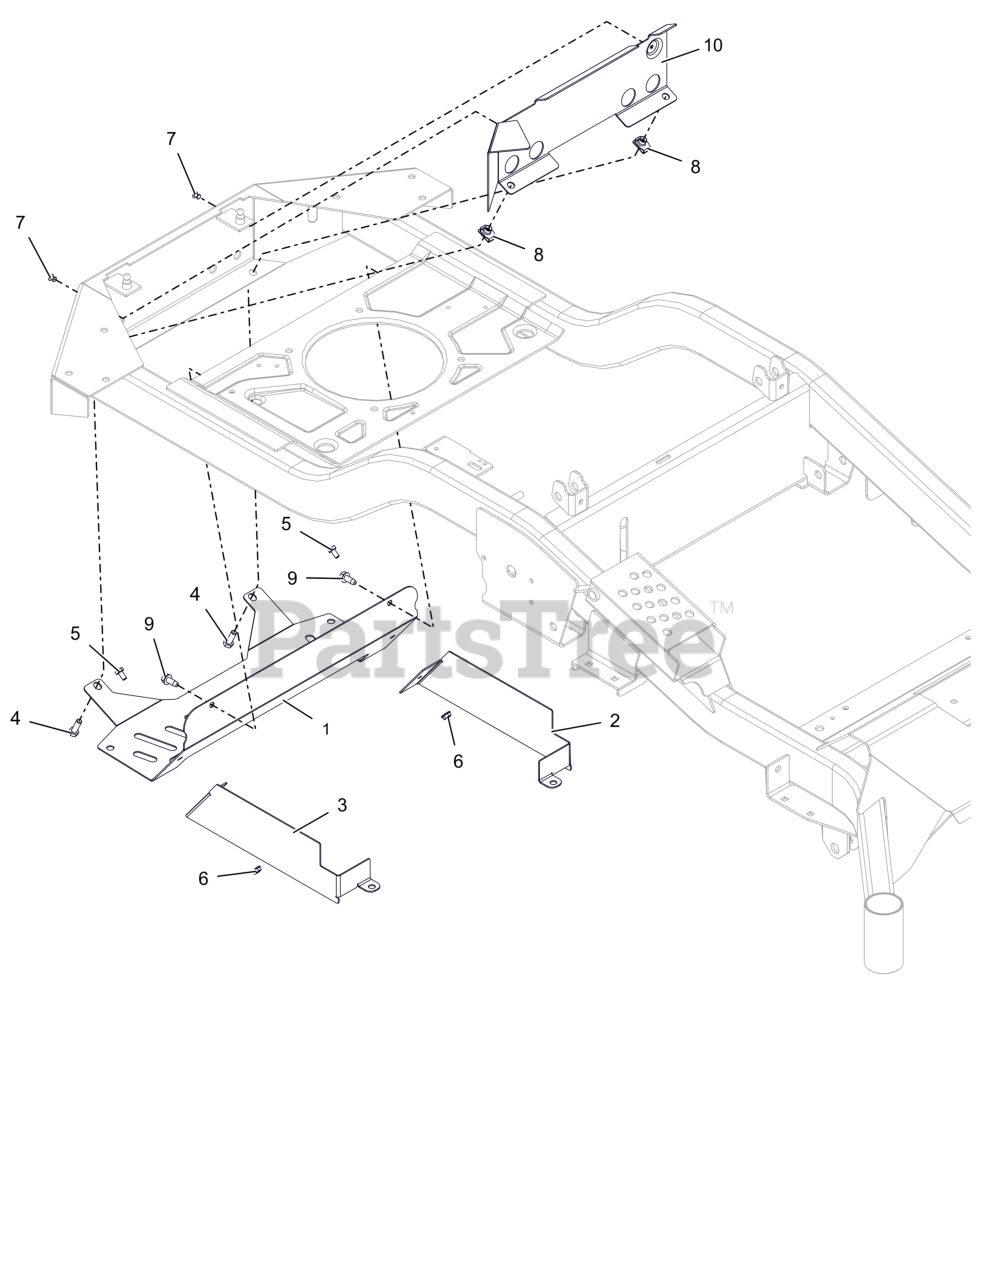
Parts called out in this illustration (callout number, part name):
1	SHIELD, HEAT (HD)
2	GUARD,REAR CLUTCH LH
3	GUARD,REAR CLUTCH RH
4	BLT,HEX .31-18X1.00 G5 ZCC
5	BLT,HEX .25-20X.50 G5 ZCC
6	NUT-LK-TOP-FLG .250-20 GF ZCC
7	RVT-POP .187x.250 (#64) BLK
8	NUT-CLIP RETAINER 5/16-18X.56
9	SCR,TAP .312-18X.75 HWH TR ZCC
10	BAFFLE, HEAT SHIELD (BLACK)
